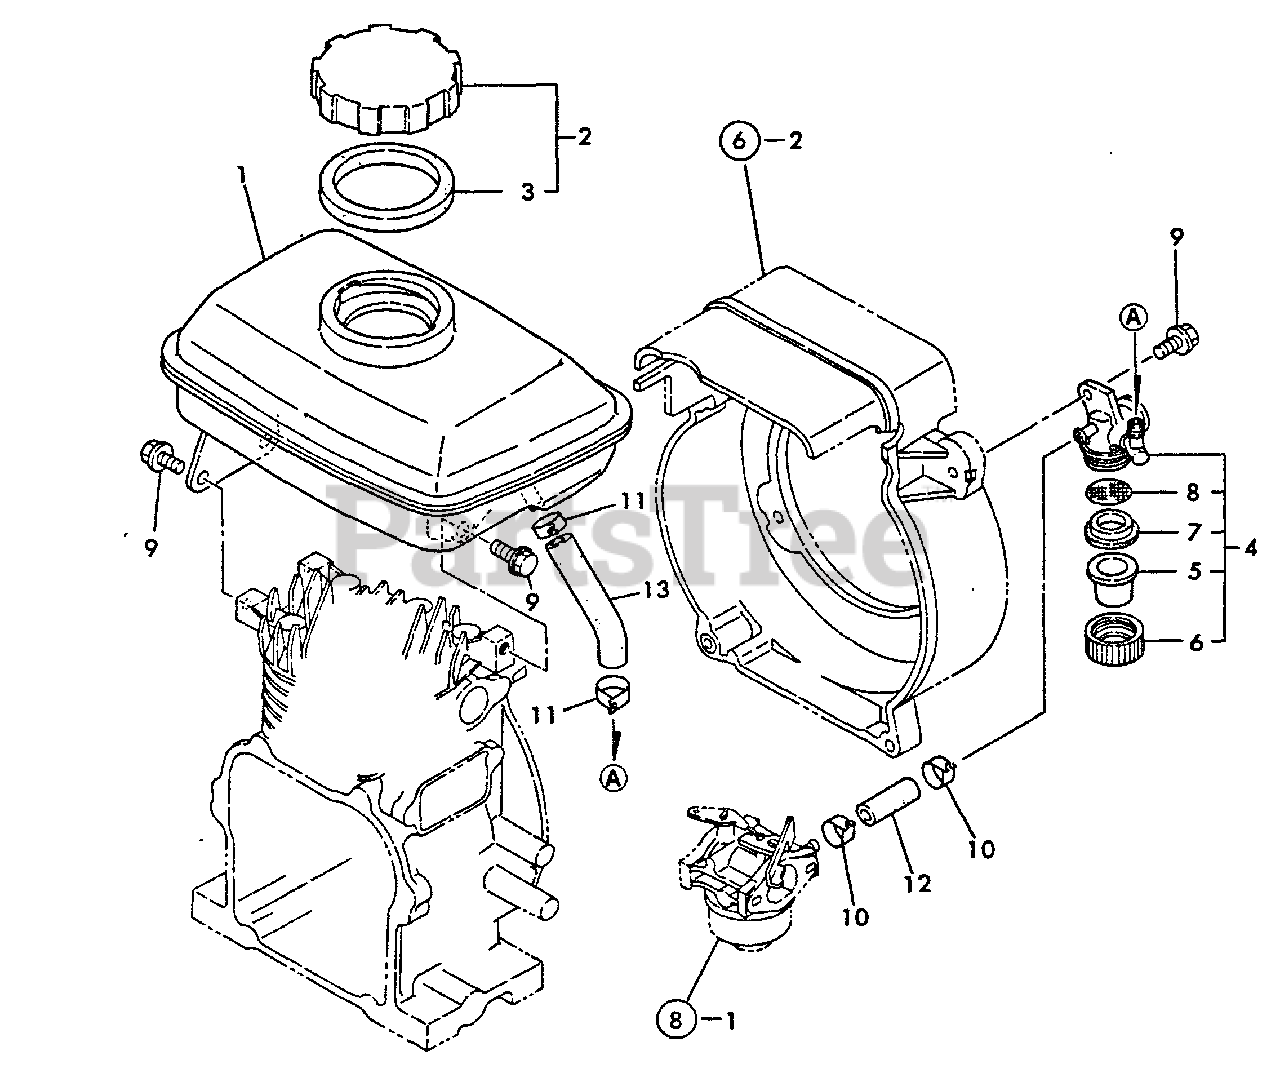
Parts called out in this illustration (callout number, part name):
1	FUEL TANK ASSY
2	CAP ASSY
3	GASKET
4	COCK ASSY, FUEL
5	BOWL, STRAINER
6	RETAINER
7	GASKET
8	FILTER, FUEL
9	BOLT - 6×8 -- PLATED
10	CLAMP, HOSE - 9
11	CLAMP, HOSE
12	PIPE, FUEL
13	PIPE, FUEL
